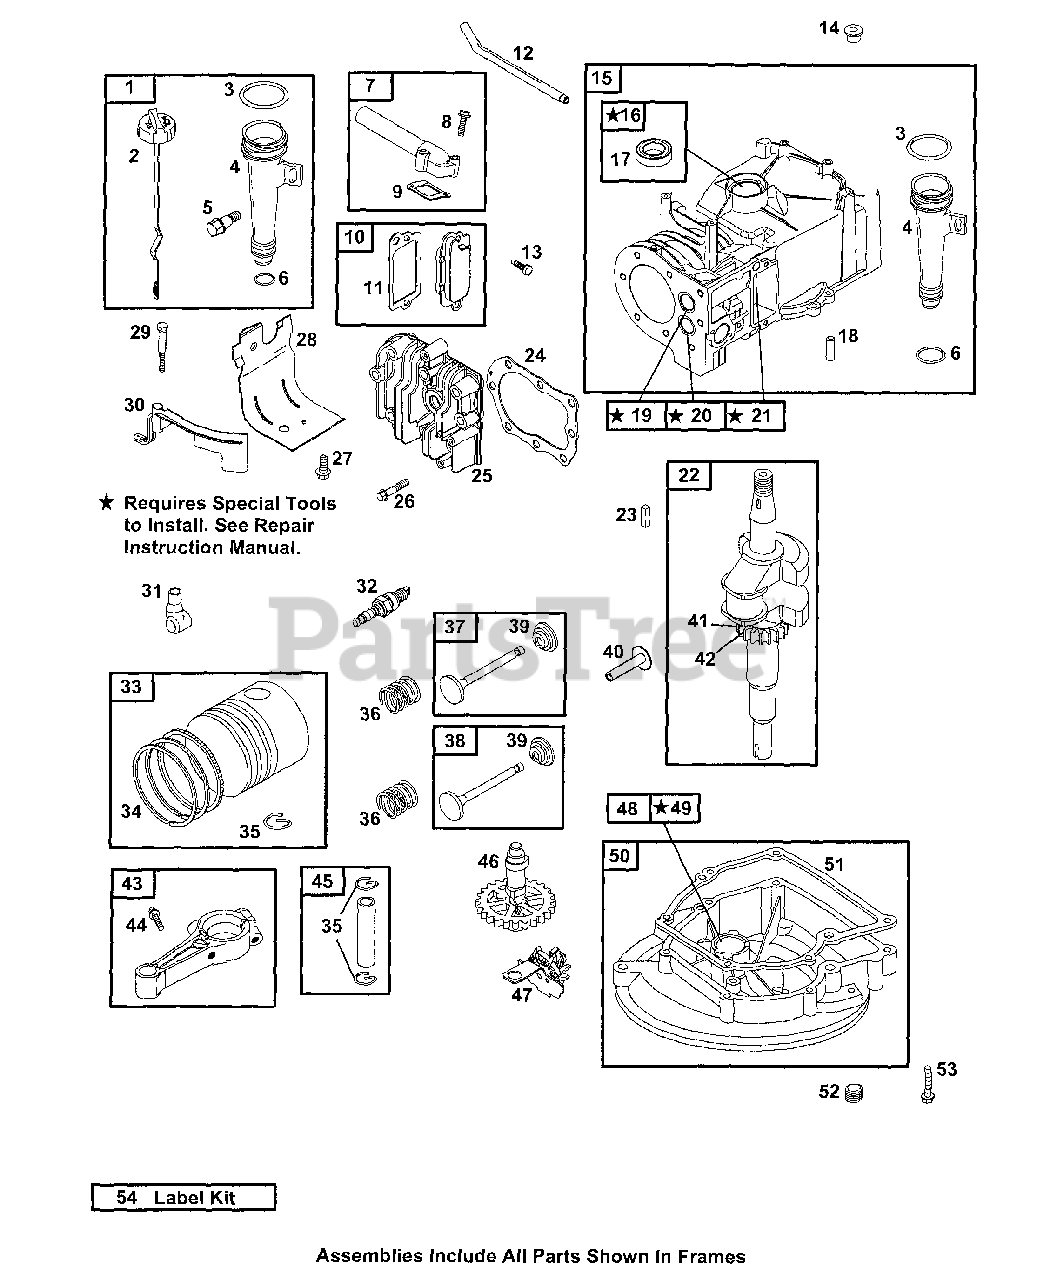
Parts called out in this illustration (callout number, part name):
1	Dipstick/ Tube Assembly
3	Dipstick/Tube Seal
4	Dipstick Tube
5	Screw (Dipstick Tube)
6	Dipstick Tube Seal
7	Intake Manifold
8	Screw (Intake Manifold)
9	Intake Gasket
10	Breather Assembly
11	Breather Gasket
12	Breather Tube
13	Screw (Breather Assembly)
15	Cylinder Assembly
16	Bushing/Seal Kit
17	Oil Seal (Magneto Side)
18	Locating Pin
19	Valve Seat (Intake)
20	Valve Seat (Exhaust)
21	Guide Bushing (Exhaust Valve)
22	Crankshaft
23	Flywheel Key
24	Cylinder Head Gasket
25	Cylinder Head
26	Screw (Cylinder Head)
27	Screw (Cylinder Shield)
28	Cylinder Shield
29	Screw (Governor Blade)
30	Governor Blade
31	Spark Plug Boot
32	Spark Plug
33	Piston Assembly
34	Ring Set
35	Piston Pin Lock
36	Valve Spring
37	Exhaust Valve
38	Intake Valve
39	Valve Retainer
40	Valve Tappet
41	Locating Pin
42	Timing Gear
43	Connecting Rod
44	Screw (Connecting Rod)
45	Piston Pin
47	Governor/Oil Slinger
48	Oil Seal (PTO Side)
49	Bushing/Seal Kit (PTO Side)
50	Engine Sump
51	Crankcase Gasket (.015 Thick, Std)
52	Oil Drain Plug
53	Screw (Crankcase Cover)
